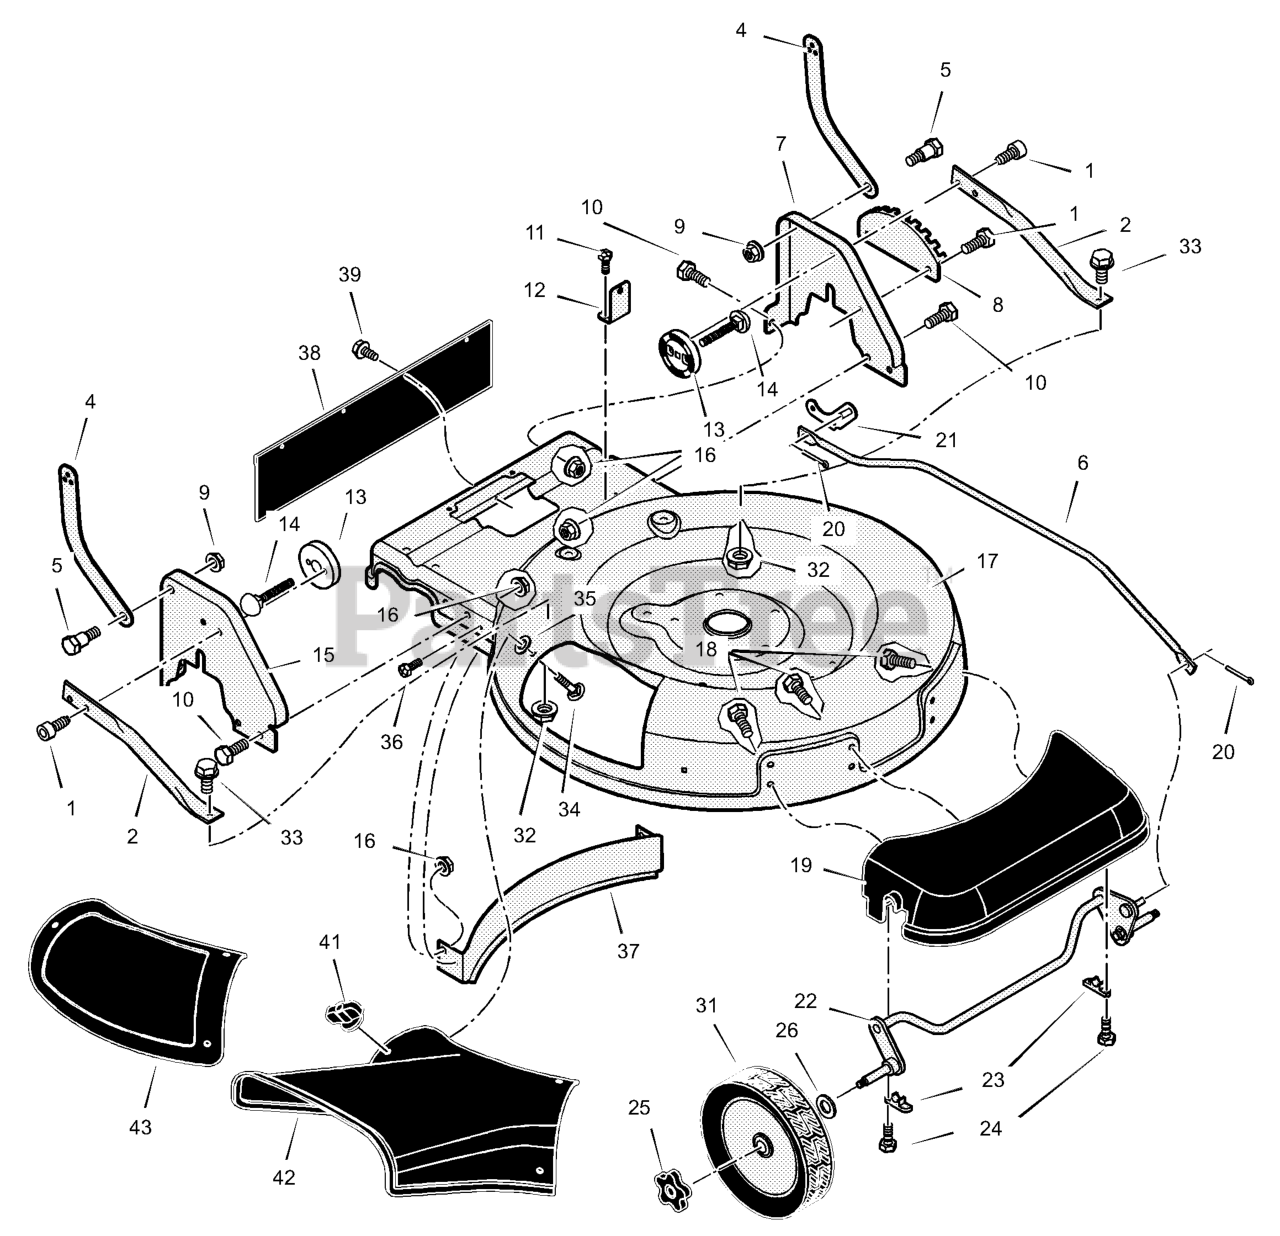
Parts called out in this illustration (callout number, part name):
2	Brace, Handle Bracket
4	Support, Handle
5	Bolt, Shoulder
6	Link, Lifter
7	Bracket, Left Handle
8	Plate, Index
9	Nut, Flange
10	Screw
12	Bracket, Blade Drive Cable
13	Support, Handle Adjuster
14	Bolt, Carriage
15	Bracket, Right Handle
17	Housing, Mower
19	Panel, Front
20	Pin, Cotter
21	Bracket Assembly, Lifter
22	Crossbar Assembly, Front
23	Clip, Front
25	Knob, Axle
26	Washer, Spring
31	Wheel and Tire
32	Nut, Flange
33	Bolt, Hex
34	Bolt, Carriage
35	Retainer, Bolt
37	Baffle, Rear
38	Deflector, Rear
42	Deflector, Chute
43	Cover, Mulch
